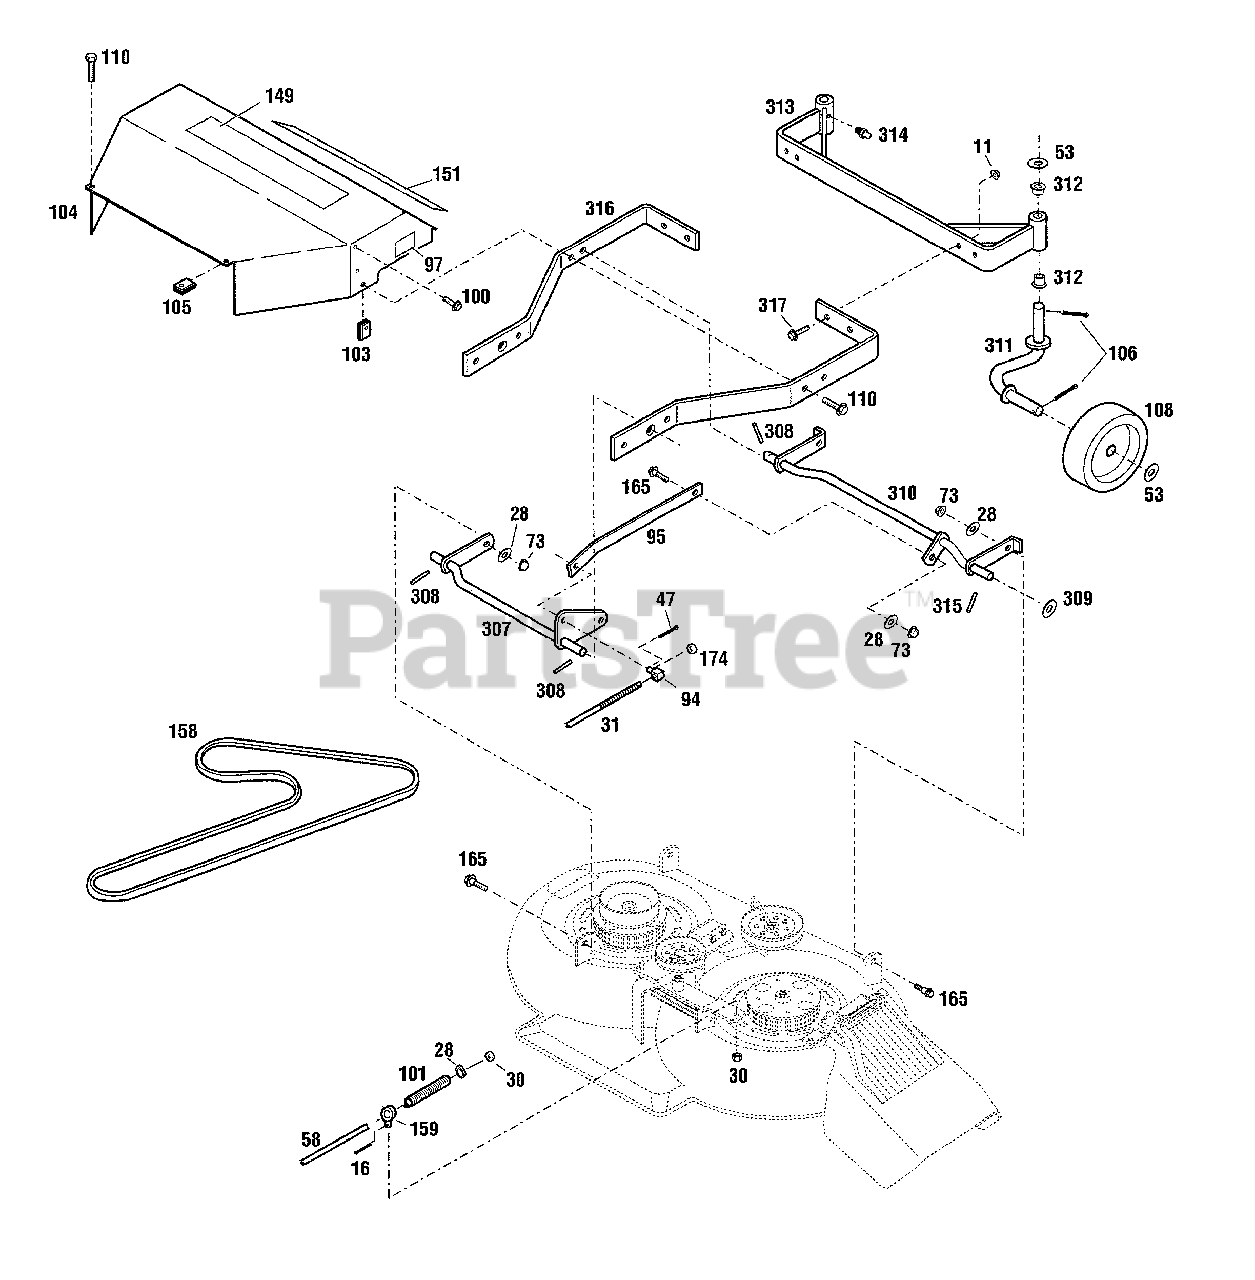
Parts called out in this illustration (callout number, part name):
11	Flange Locknut, 3/8-16
16	Cotter Pin, 3/32 x 5/8
28	Flat Washer, 3/8
30	Locknut, 3/8-16
31	Lift Crank
47	Cotter Pin
53	Special Washer
58	Lower Blade Rod
73	Flange Locknut, 3/8-16
94	Pivot Block
95	Leveler Bar
97	Cutting Height Decal
100	Tap Screw, #8 x 3/8
101	Compression Spring
103	Speed Nut, 5/16-18
104	Belt Guard
105	Speed Nut, 5/16-18
106	Cotter Pin
108	Gage Wheel
110	Flange Lock Screw, 5/16 x 3/4
149	Logo Decal
151	33" Combination Deck Decal
159	Eye Bolt
165	Shoulder Bolt
174	Toplock Nut
307	Rear Lift Assembly
308	Roll Pin, 1/4 x 1
309	Flat Washer, 5/8
310	Front Lift Assembly
311	Spindle Assembly
312	Flange Bearing
313	Gage Support
314	Grease Fitting
315	Drive Pin, 1/4 x 3
316	Mower Support
317	Whizlock Screw, 3/8-16 x 1
